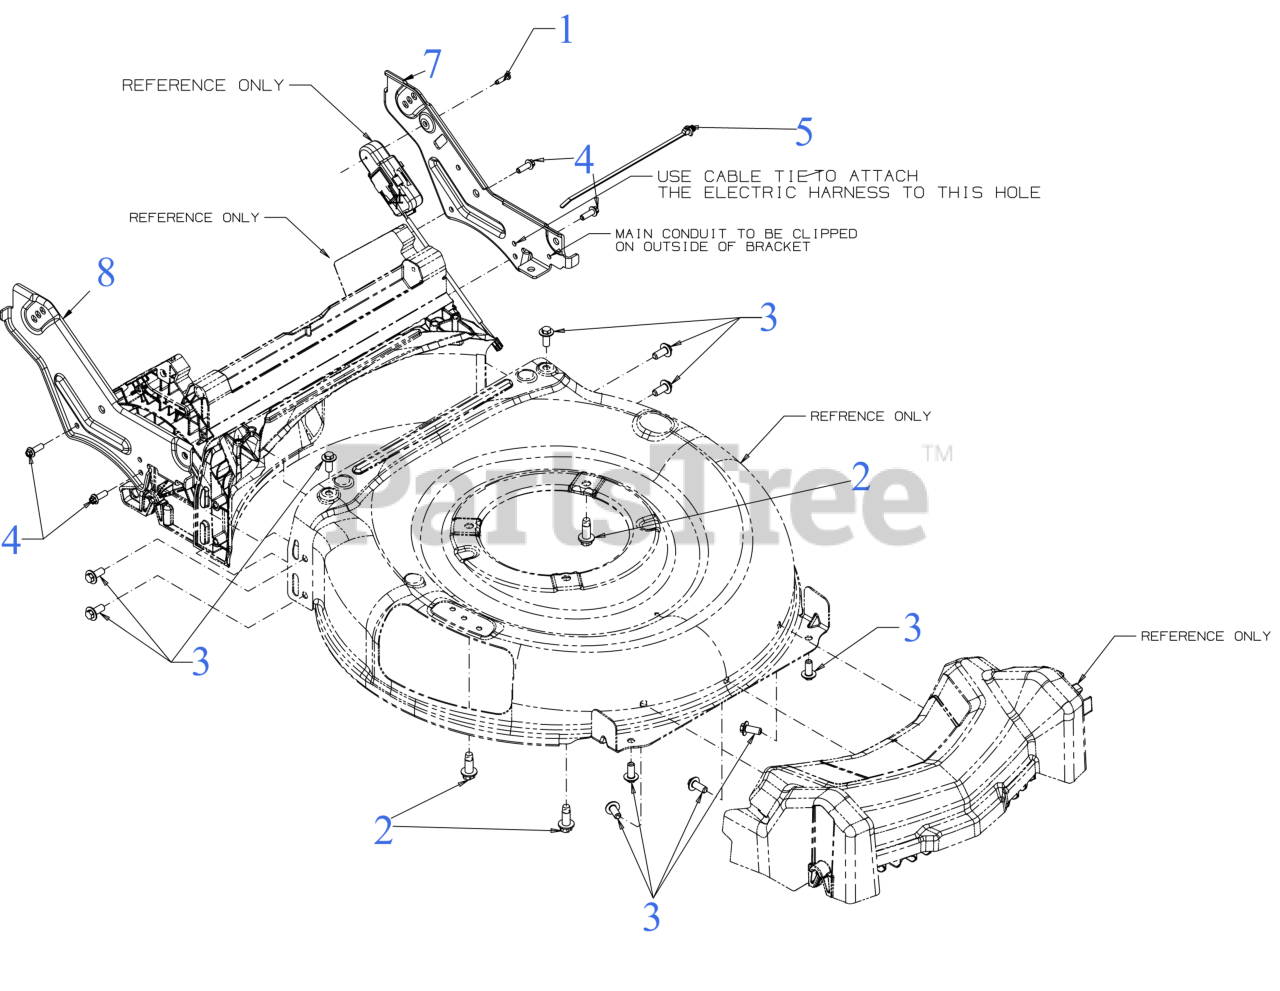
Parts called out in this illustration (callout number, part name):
1	SCREW 7-18X.75:T20
2	SCREW 3/8-16 x 1
3	SCREW 5/16-14 x .750
4	SCREW 1/4 x .750
5	CABLE TIE
7	HANDLE BRACKET (LH)
8	HANDLE BRACKET (RH)
